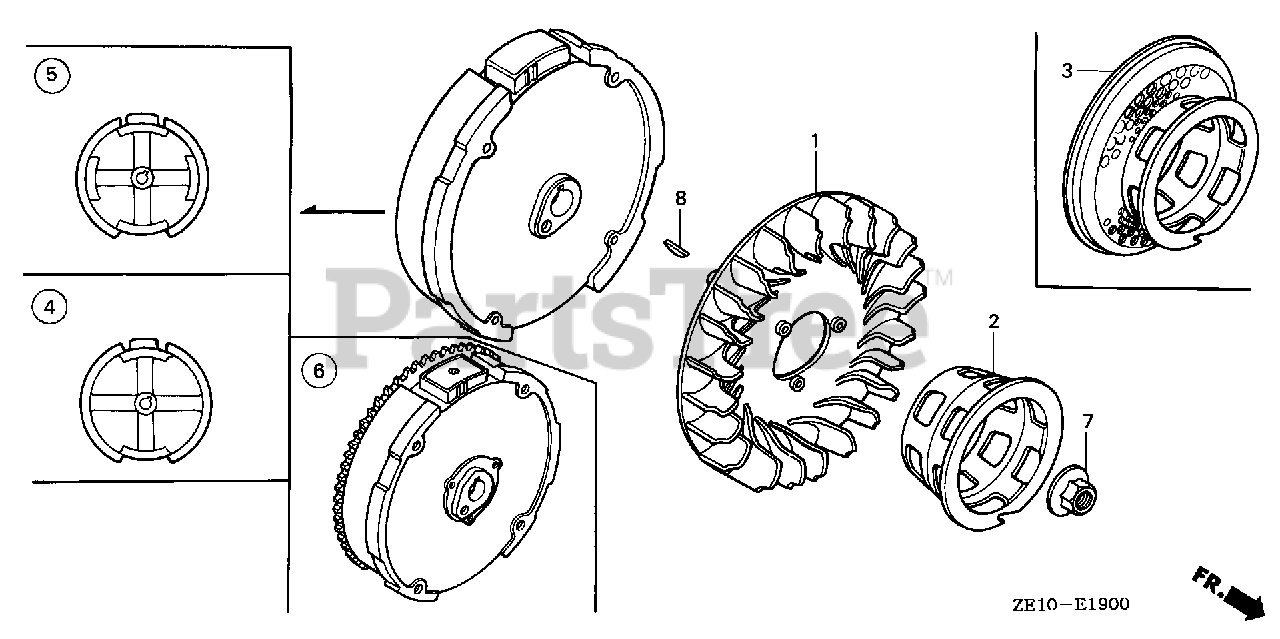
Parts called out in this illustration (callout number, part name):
1	FAN, COOLING
2	PULLEY, STARTER
4	FLYWHEEL
7	NUT, SPECIAL (14MM)
8	KEY, SPECIAL WOODRUFF (25X18)
